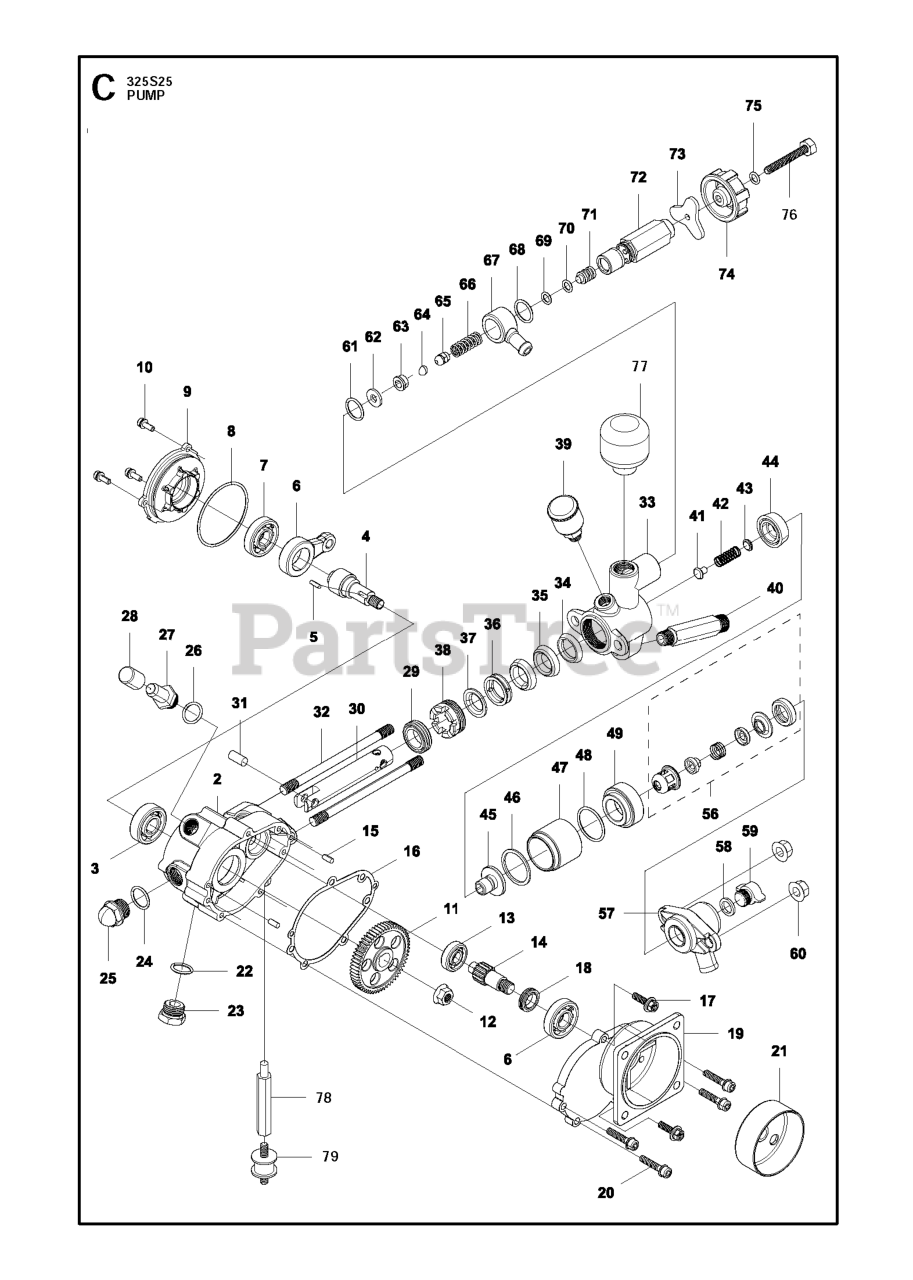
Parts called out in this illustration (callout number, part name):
3	BEARING NO.6201
4	CRANKSHAFT
6	CONNECTING
7	BEARING NO.6001
9	PUMP COVER
11	REDUCTION GEAR
13	BEARING NO.609
14	PINION SHAFT
15	PUMP BODY PIN
19	ENGINE COVER
21	CLUTCH DRUM
25	OIL MIRROR
30	PLUNGER (PISTON)
31	PISTON PIN
32	BODY SCREW
35	V-PACKING ASSY
36	GREASE PACKING
38	ADJUSTING RING
39	GREASE CUP ASSY
40	OUTLET BOLT
41	SPRING SEAT
44	HARD RUBBER
45	PLUNGER SCREW
49	VALVE SEAT
56	VALVE ASSY
57	SUCTION CHAMBER
64	PRESSURE BALL
65	SPRING SEAT
66	PRESSURE SPRING
67	OVERFLOW CONNECTOR
71	REGULATOR SHAFT
72	PRESSURE PIPE
74	PRESSURE PLATE
75	SET WASHER (2/set)
77	AIR CHAMBER
78	STRUT BOLT
79	RUBBER CRANKCASE STAND
